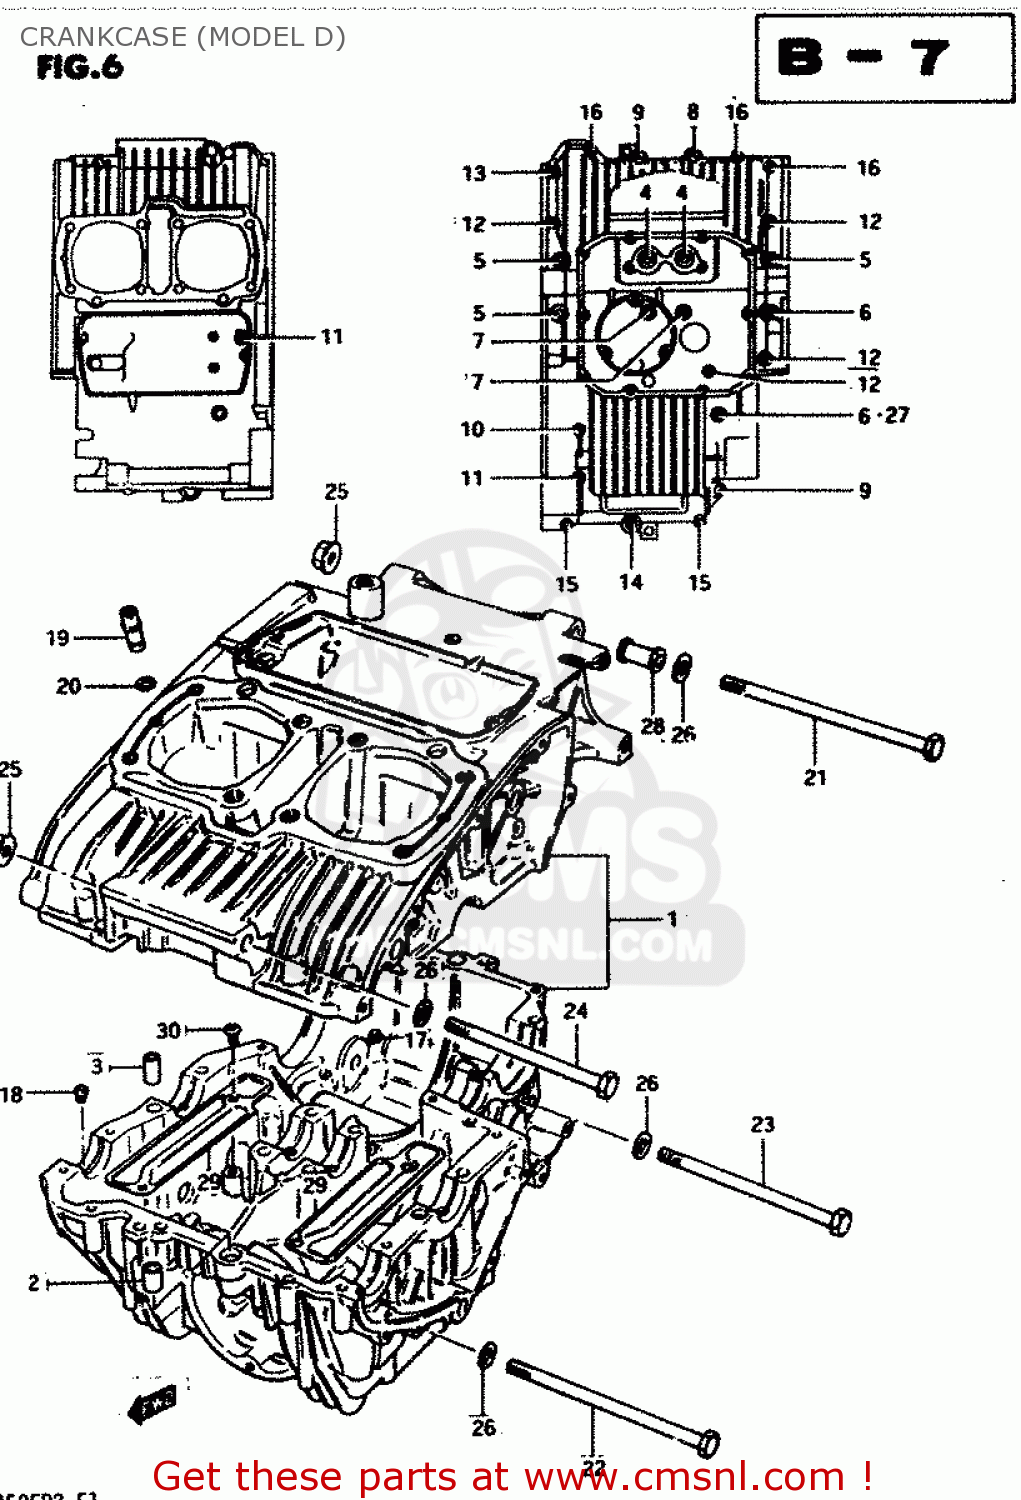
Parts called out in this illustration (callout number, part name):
1	CRANKCASE SET
2	PIN(10.4X13X22)
3	PIN (11X20)(SUS)
4	BOLT
5	BOLT
6	BOLT
7	BOLT
8	BOLT (8X65)
9	BOLT
10	BOLT(6X125)
11	BOLT(6X105)
12	BOLT (6X90)
13	BOLT
14	BOLT
15	BOLT 6X50
16	BOLT (6X45)
17	JET,AIR
18	JET
19	JET
20	O RING(D:1.05,ID:3.1)
21	BOLT
22	BOLT
23	BOLT
24	BOLT
25	NUT 10MM
26	WASHER
27	GASKET 8.2X14X1 (NAS)
28	SPACER,ENGINE MOUNT
29	PLATE,OIL SEPARATOR
30	SCREW
